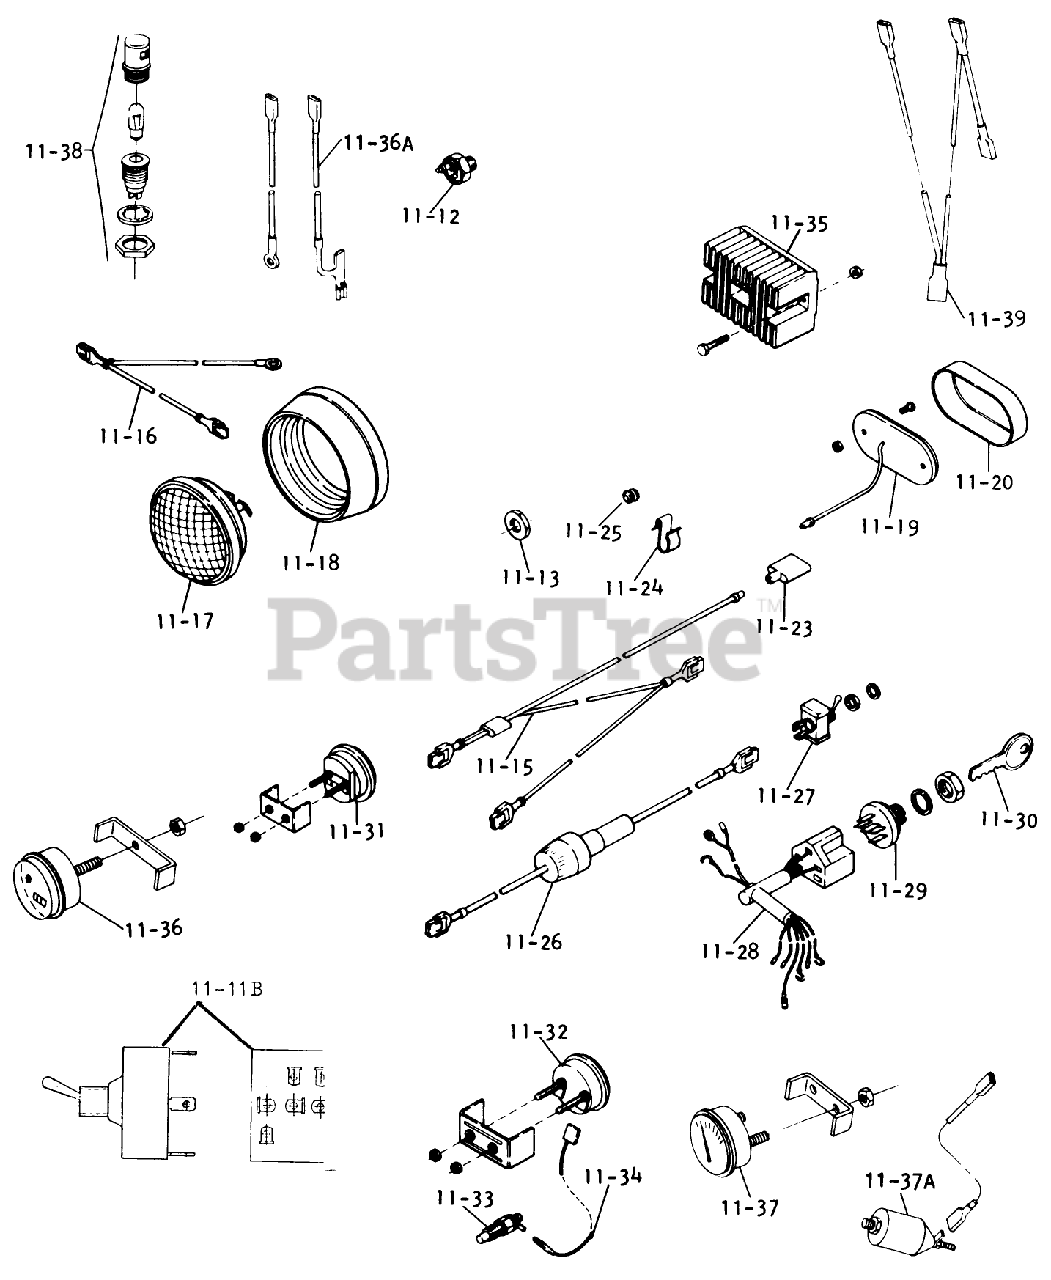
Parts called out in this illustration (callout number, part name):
11-12	SWITCH SAFETY
11-13	NUT-SPECIAL 9/16-18
11-17	HEADLAMP
11-20	HEX NUT 10-32 E.S. + + USE 3296-21 + +
11-27	SWITCH-LIGHTS
11-27	NUT-HEX
11-29	SWITCH-IGNITION
11-31	HEX NUT 10-32 E.S. + + USE 3296-21 + +
11-32	HEX NUT 10-32 E.S. + + USE 3296-21 + +
11-35	REGULATOR-RECTIFIER
11-37	HEX NUT 10-32 E.S. + + USE 3296-21 + +
